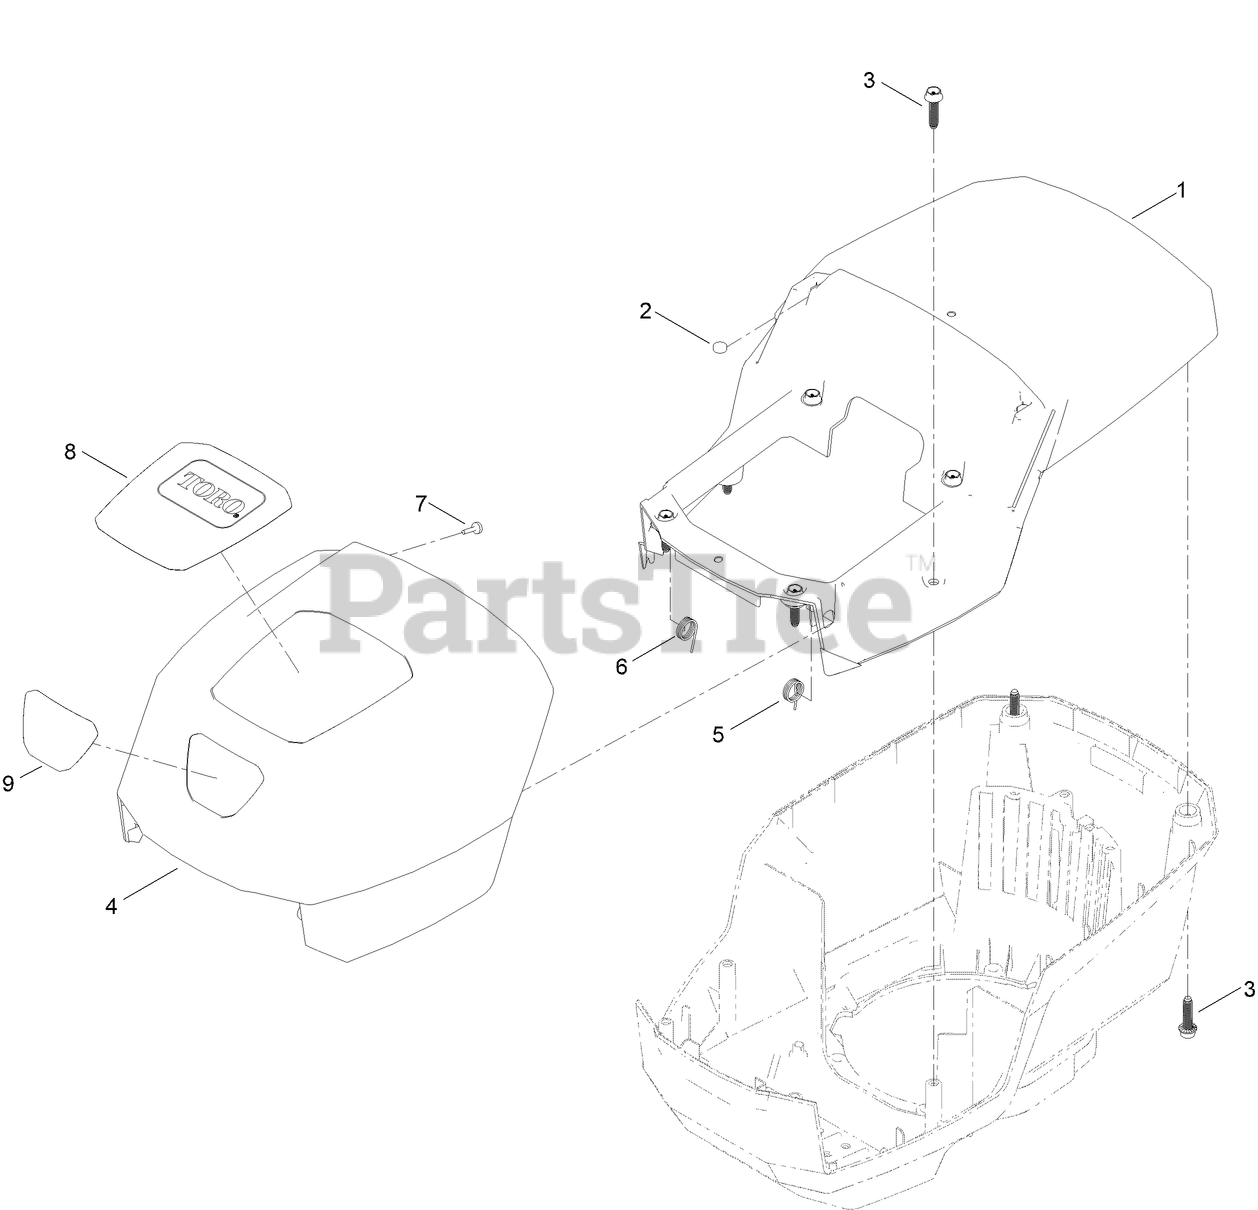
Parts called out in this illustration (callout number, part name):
1	SHROUD-UPPER
2	MAGNET
3	SCREW-FLANGE, PLASTIC
5	SPRING-LH
6	SPRING-RH
7	SCREW-PPH
8	DECAL-HOOD, TOP
9	DECAL-HOOD, FRONT
